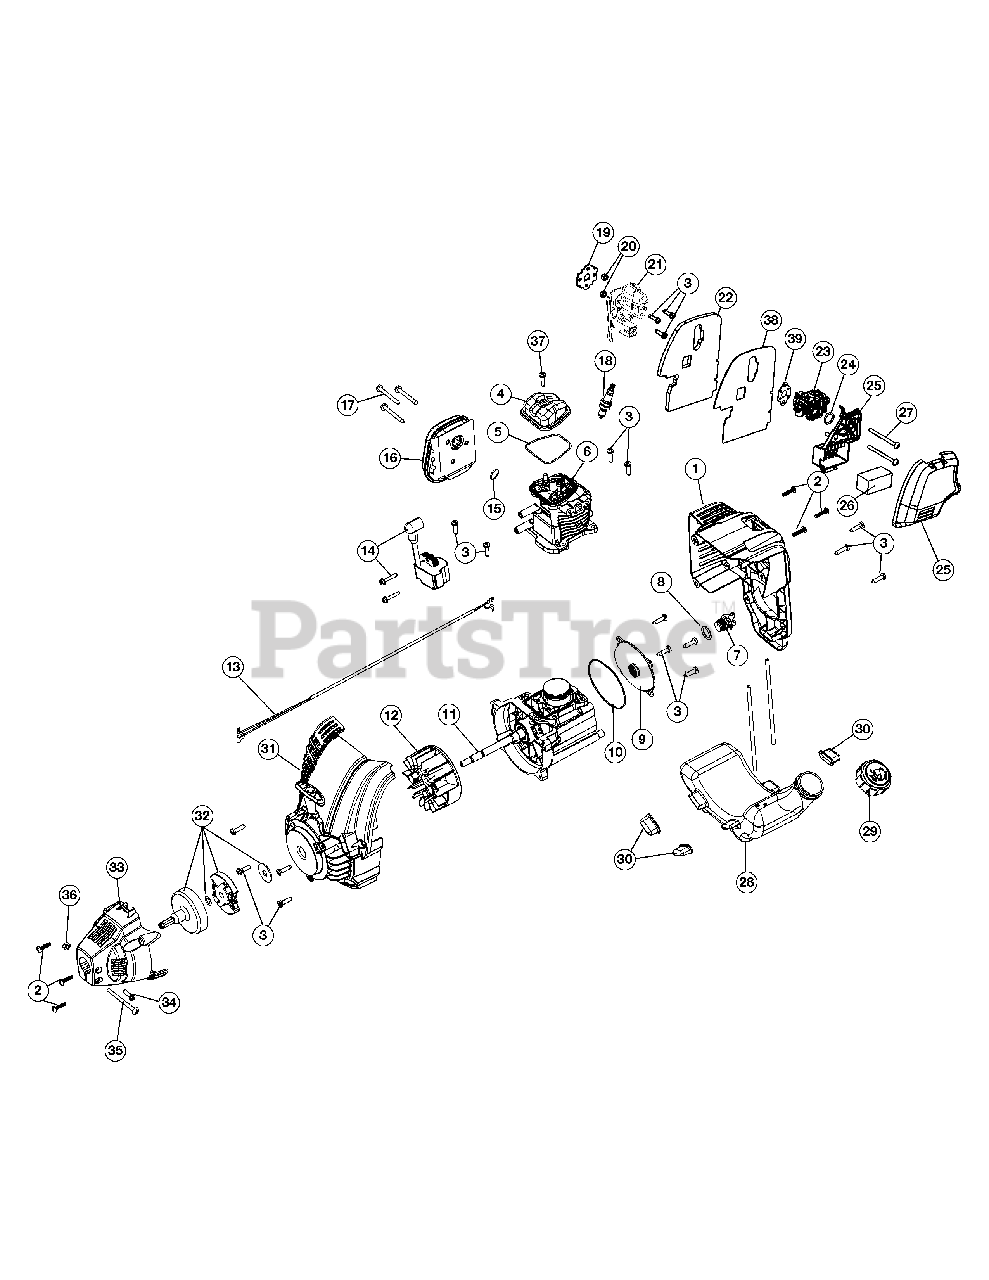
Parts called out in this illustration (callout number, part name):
1	Engine Cover Assembly (Incl. 2 & 3)
2	Cover Screw
3	Screw
4	Rocker Cover
5	Rocker Cover O-Ring
6	Cylinder Assembly (Incl. 3 & 5)
7	Oil Plug (Incl. 8)
8	Oil Plug O-Ring
9	Crankcase Cover
10	Crankcase Cover O-ring
11	Crankcase Assembly (Incl. 10)
12	Flywheel Assembly
13	Lead Wires
14	Module Assembly
15	Muffler Gasket
16	Muffler Assembly (Incl. 15 & 17)
17	Muffler Screw
18	Spark Plug
19	Insulator Gasket
21	Insulator
22	Heat Shield
23	Carburetor
25	Air Cleaner Cover Assembly (Incl. 26)
26	Air Filter
28	Fuel Tank Assembly w/Fuel Lines (Incl. 29)
29	Fuel Cap
30	Fuel Tank Pads
31	Starter Housing Assembly (Incl. 3)
32	Clutch Assembly
33	Clutch Cover (Incl. 2)
34	Anti-Rotation Screw
35	Clamp Screw
37	Rocker Cover Screw
38	Gasket
